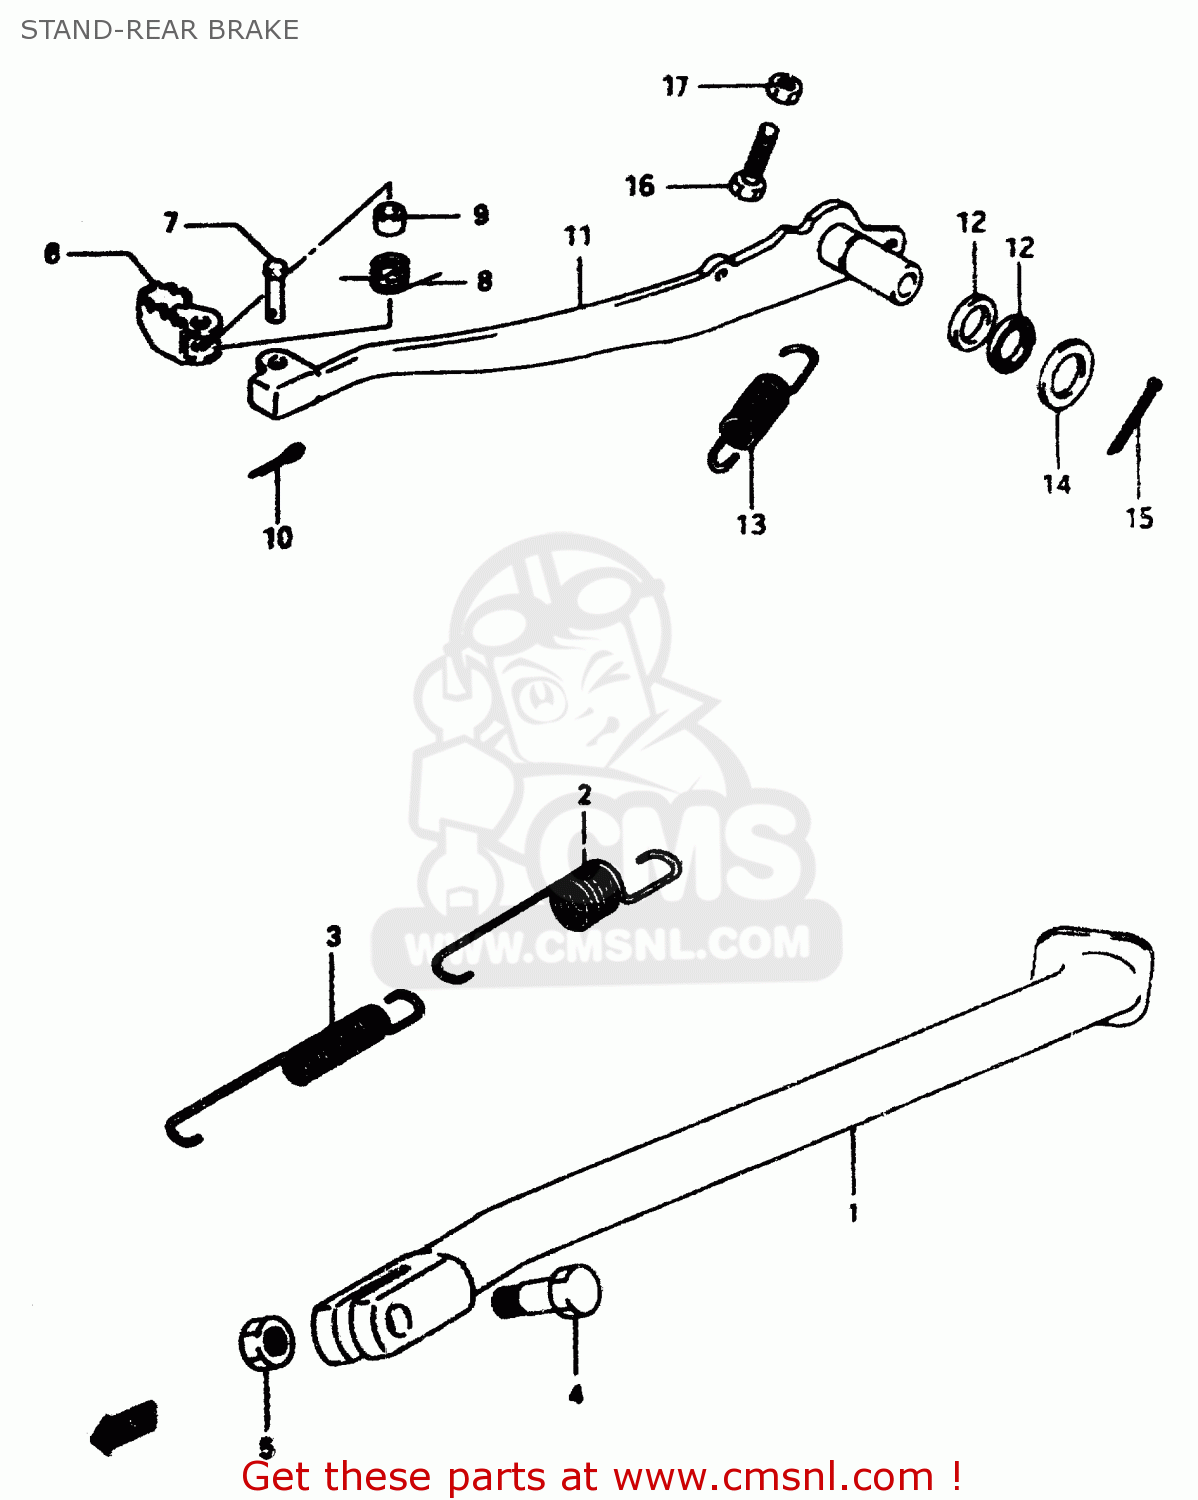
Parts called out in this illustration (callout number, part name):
1	STAND,PROP(BLACK)
2	SPRING
3	SPRING
4	BOLT(10X30)
5	NUT
6	PEDAL,BRAKE
7	PIN
8	SPRING
9	SPACER(6.5X9X6.5)
10	PIN
11	ARM,BRAKE PEDAL
12	SEAL,OIL(15X21X3)
13	SPRING
14	WASHER(15.5X26X2.3)
15	COTTER PIN
16	BOLT(6X23)
17	NUT 6MM
